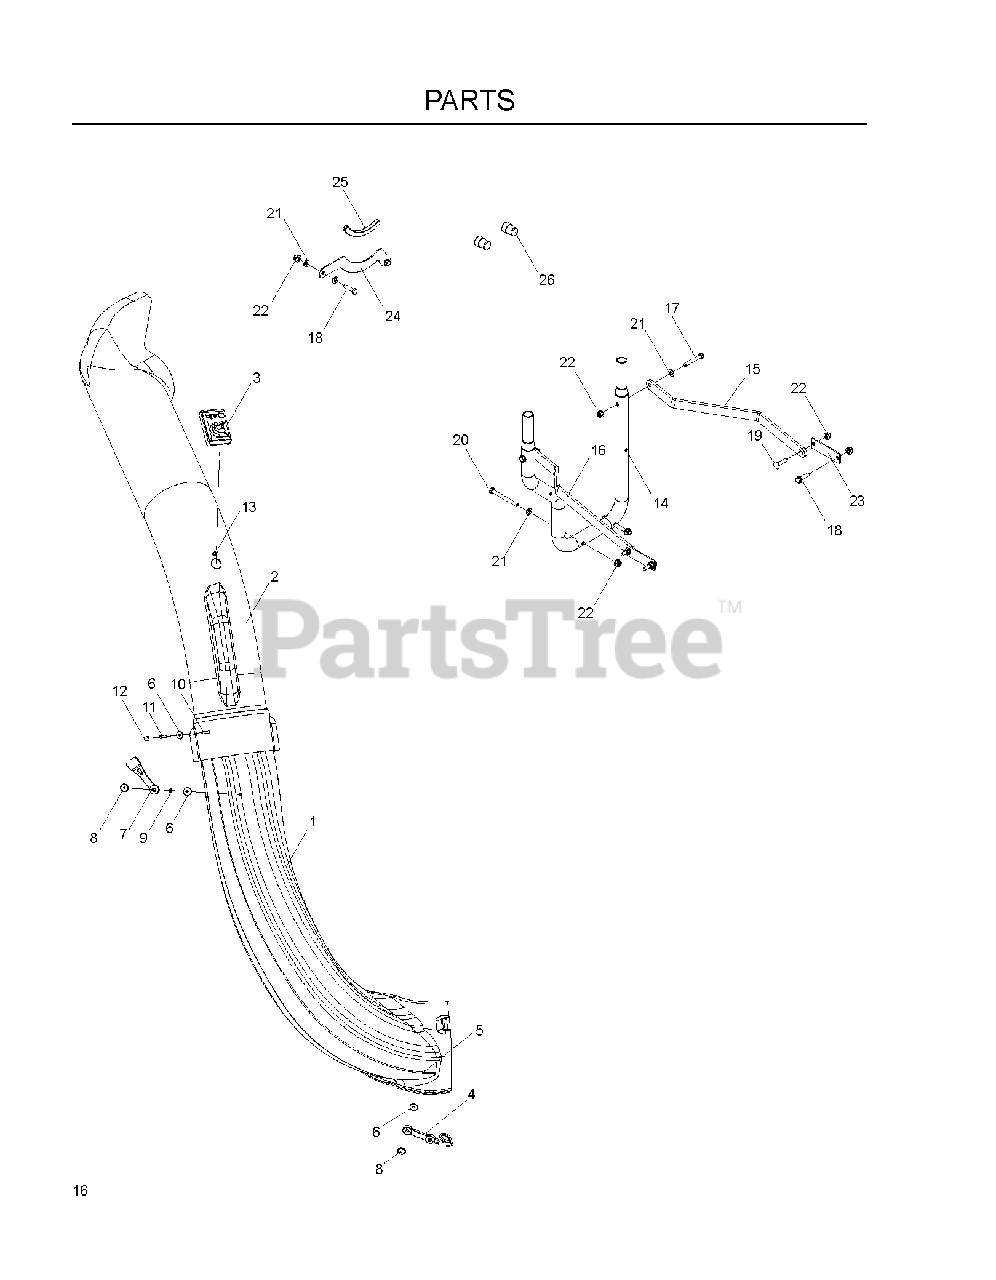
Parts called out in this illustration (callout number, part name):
1	Bagger Chute, Lower 54"
2	CHUTE.COLLECTION.UPPER
3	DUMP BAG INDICATOR
4	LATCH ASSY TBR
5	SCREW #10-24 X 5/8
7	HOOD LATCH
8	NUT 10-24 WELD PLATED
9	WASHER - 3/16 LOCK ZD
10	SCREW #10-24 X 1-1/8 ZD SPEC
11	BSHG .202X.75 LG SPLIT ZD SPEC
12	NUT 10-24 ACORN ZD
13	SCREW
14	MOUNT.TUBE.COLLECTIONS
15	STRAP, SUPPORT, LT BLK
16	STRAP, SUPPORT, RT BLK
17	HCS 5/16-18X2
18	HCS 5/16C X 1 1/4
19	BRACKET DEFLECTOR MOWER 42
20	HCS 5/16-18 X 3 1/4
21	FLAT WASHER 5/16 SAE
22	5/16-18 NYLOC FLANGE NUT
23	REINFORCEMENT PLATE BLK
24	SUPPORT.CHUTE.COLLECTION.BLACK
25	Flex Trim, 1' Black
26	SPACER PLUG, BAGGER
